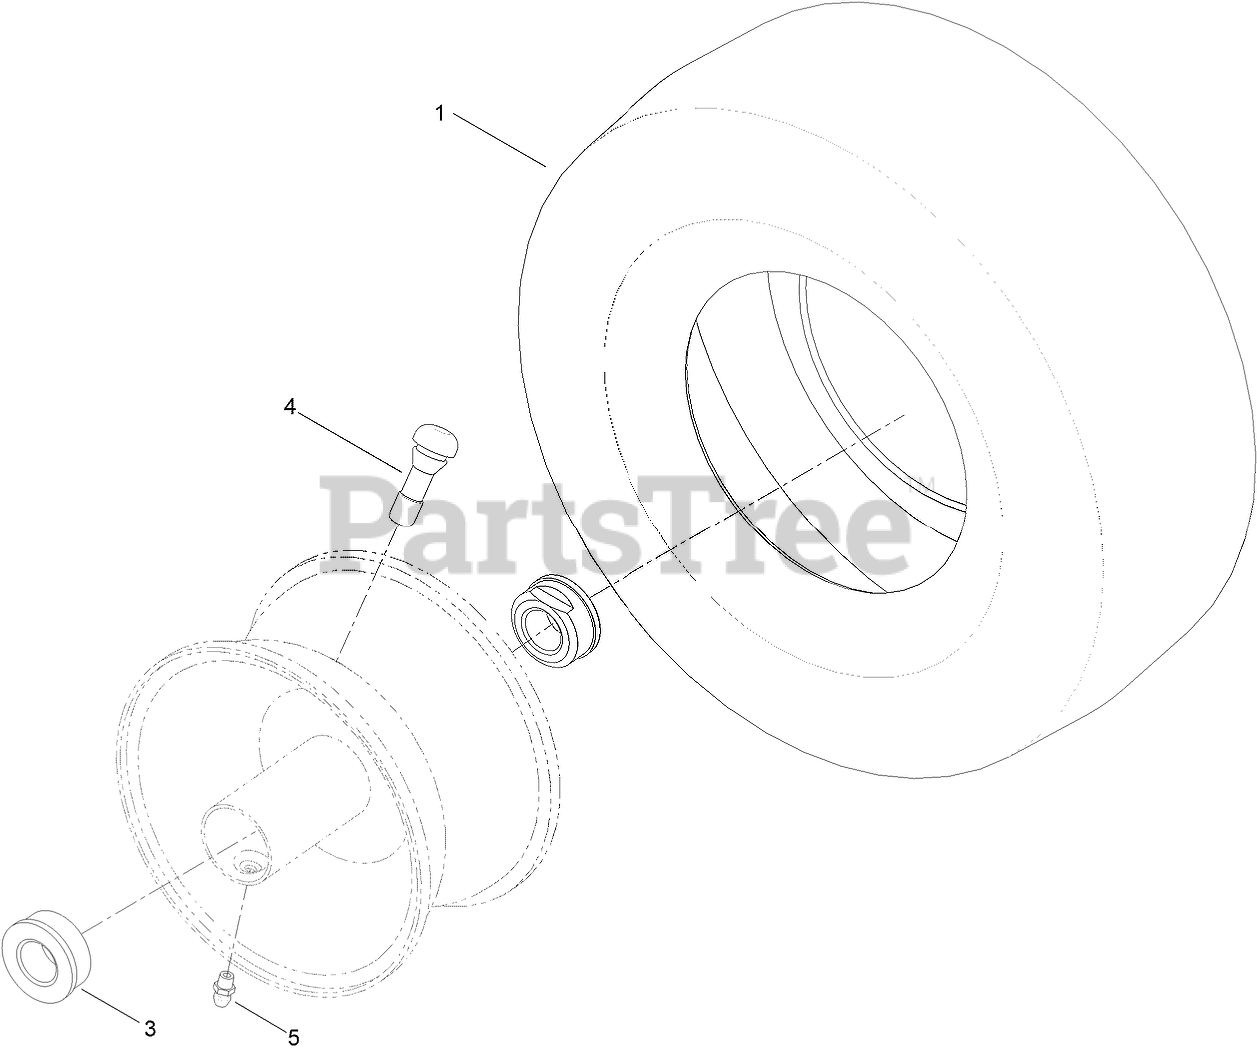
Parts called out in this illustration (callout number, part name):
1	TIRE-13 INCH SMOOTH
3	BUSHING-FLANGE
4	STEM-VALVE
5	FITTING-GREASE
